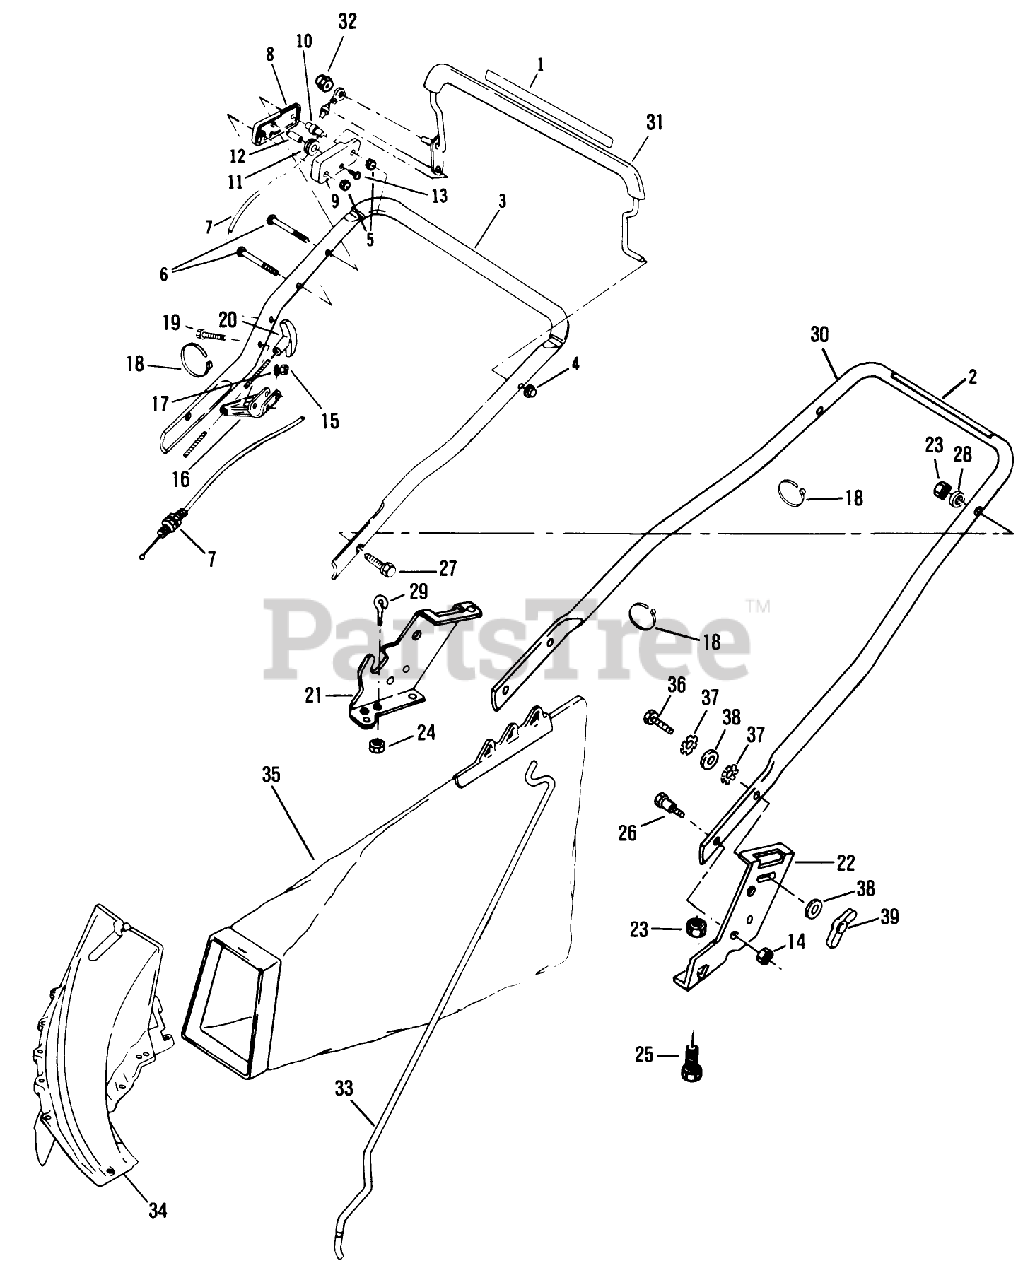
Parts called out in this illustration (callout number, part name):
3	HANDLE SECTION TOP
5	NUT C/LOCK E
7	CONTROL CABLE WES
10	COLUMN
12	PIN SKF
13	SCREW
14	NUT-JAM, LOCKING
15	LOCKNUT E
17	WASHER
19	Screw-Truss Head
20	HANDLE START UM&D
23	NUT-LOCK F
24	LOCKNUT E
26	BOLT
28	WASHER-CURVED
29	BOLT-EYE
32	NUT ACORN
33	ROD GRASSBAG
35	89802 LB WHOLE GOODS
37	LOCK WASHER LARSON
38	WASHER
39	NUT-WING
